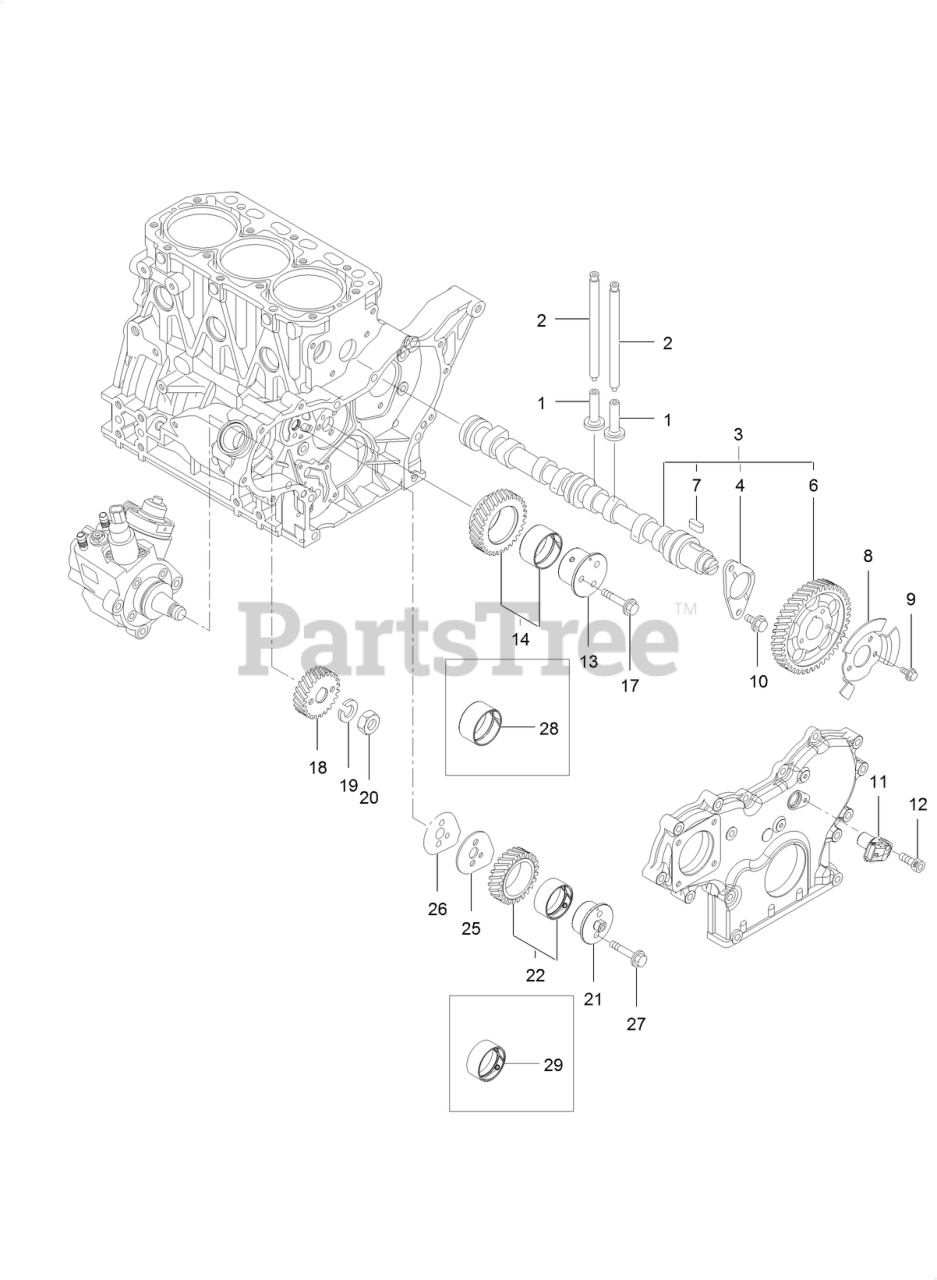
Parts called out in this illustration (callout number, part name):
1	TAPPET
2	ROD-PUSH
3	CAMSHAFT ASM
4	METAL-THRUST
7	GEAR-CAMSHAFT
8	PULSER-CAMSHAFT
11	SENSOR-REV, GEAR
13	SHAFT-IDLE, GEAR A
14	IDLE GEAR A ASM
18	GEAR-PUMP, SUPPLY
19	WASHER-SPRING
20	NUT-LOCK
21	SHAFT-IDLE, GEAR B
22	IDLE GEAR B ASM
25	PLATE-IDLE, SHAFT
26	GASKET-IDLE, SHAFT B
28	BUSHING
29	BUSHING
